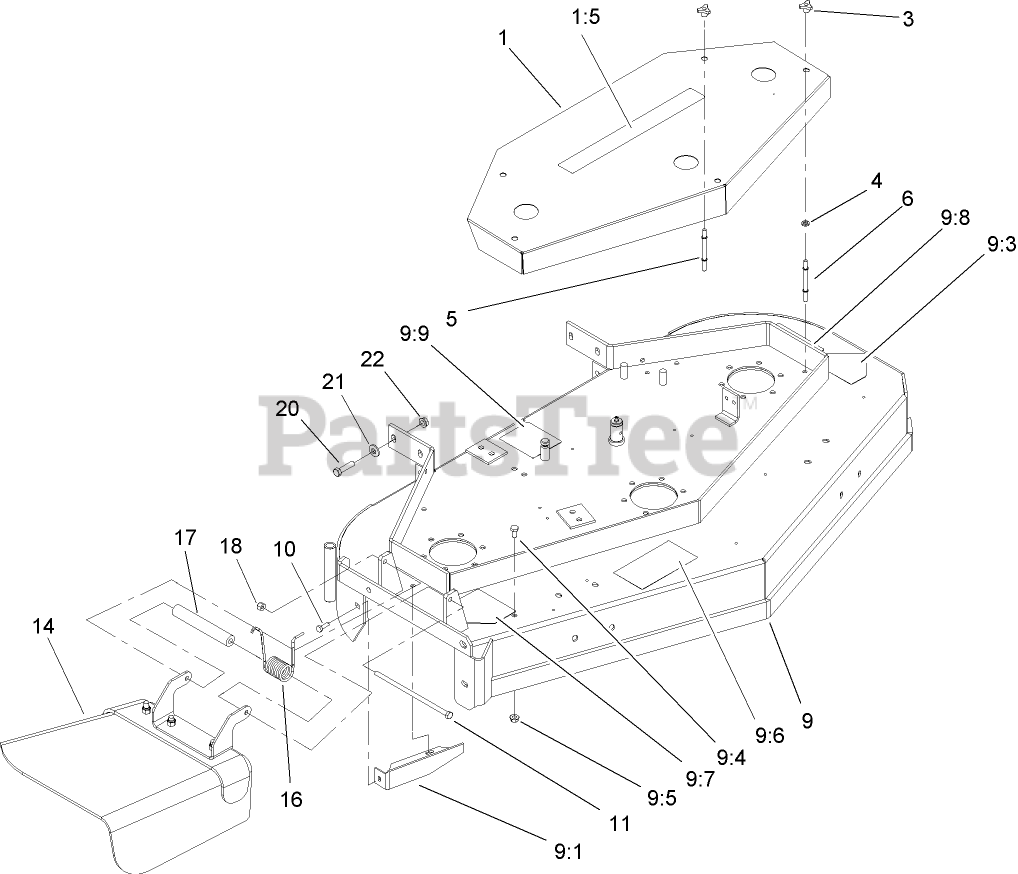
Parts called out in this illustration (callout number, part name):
1	SHIELD-BELT
3	KNOB-HANDLE
4	WASHER
5	STUD-SHIELD, BELT (LONG)
6	STUD-SHIELD, BELT (SHORT)
9	DECK ASM
9:1	BAFFLE-DOGLEG
9:3	DECAL-DANGER
9:4	SCREW-HH
9:5	NUT-HF
9:6	DECAL-DANGER, THROWN OBJECT
9:7	DECAL-DANGER
9:8	DECAL-TORQUE, BOLT
9:9	DECAL-ROUTING, BELT
10	SCREW-HH
11	SCREW-HH
14	DEFLECTOR ASM
16	SPRING-TORSION
17	SPACER
18	NUT-LOCK, NI
20	SCREW-HH
21	WASHER-BELLEVILLE
22	NUT-HHF, WHIZ
